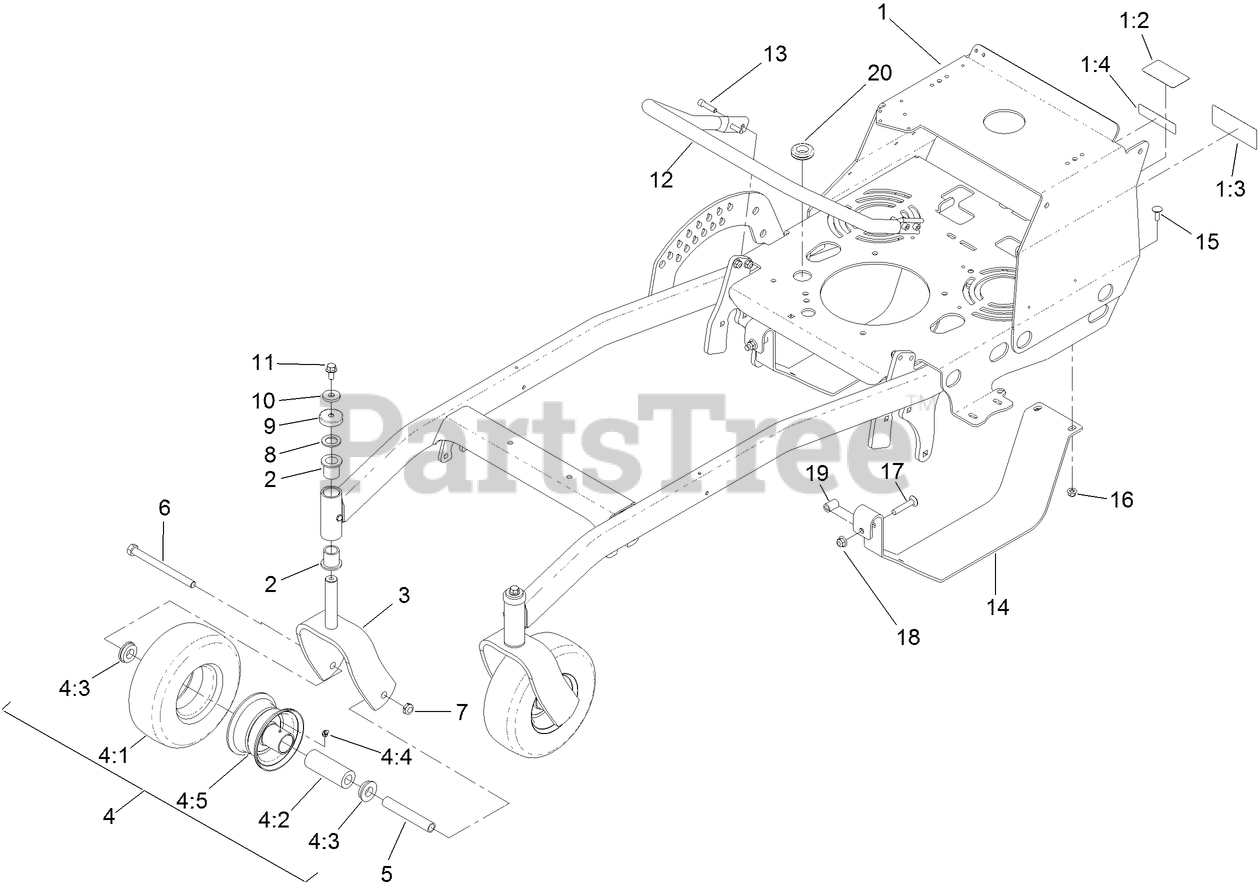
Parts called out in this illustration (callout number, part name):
1	FRAME ASM
1:2	DECAL - BYPASS
1:3	DECAL-WARNING, SULKY
1:4	DECAL-WARNING
2	BEARING-FLANGED
3	FORK, CASTER
4	WHEEL AND TIRE ASM
4:1	TIRE
4:2	BEARING
4:3	BUSHING
4:4	FITTING-GREASE
4:5	WHEEL - 4 X 2.25 X 4.25 TUBE
5	SPACER
6	SCREW-HH
7	NUT-HEX
8	WASHER-THRUST
9	CAP, DUST
10	WASHER
11	SCREW-HHF
12	TUBE, MUFFLER GUARD
13	SCREW-HSH
14	GUARD-TRANSMISSION
15	BOLT-CARR
16	NUT-HF, NI
17	BOLT-CARRIAGE
18	NUT-HF, NI
19	SPACER
20	GROMMET
